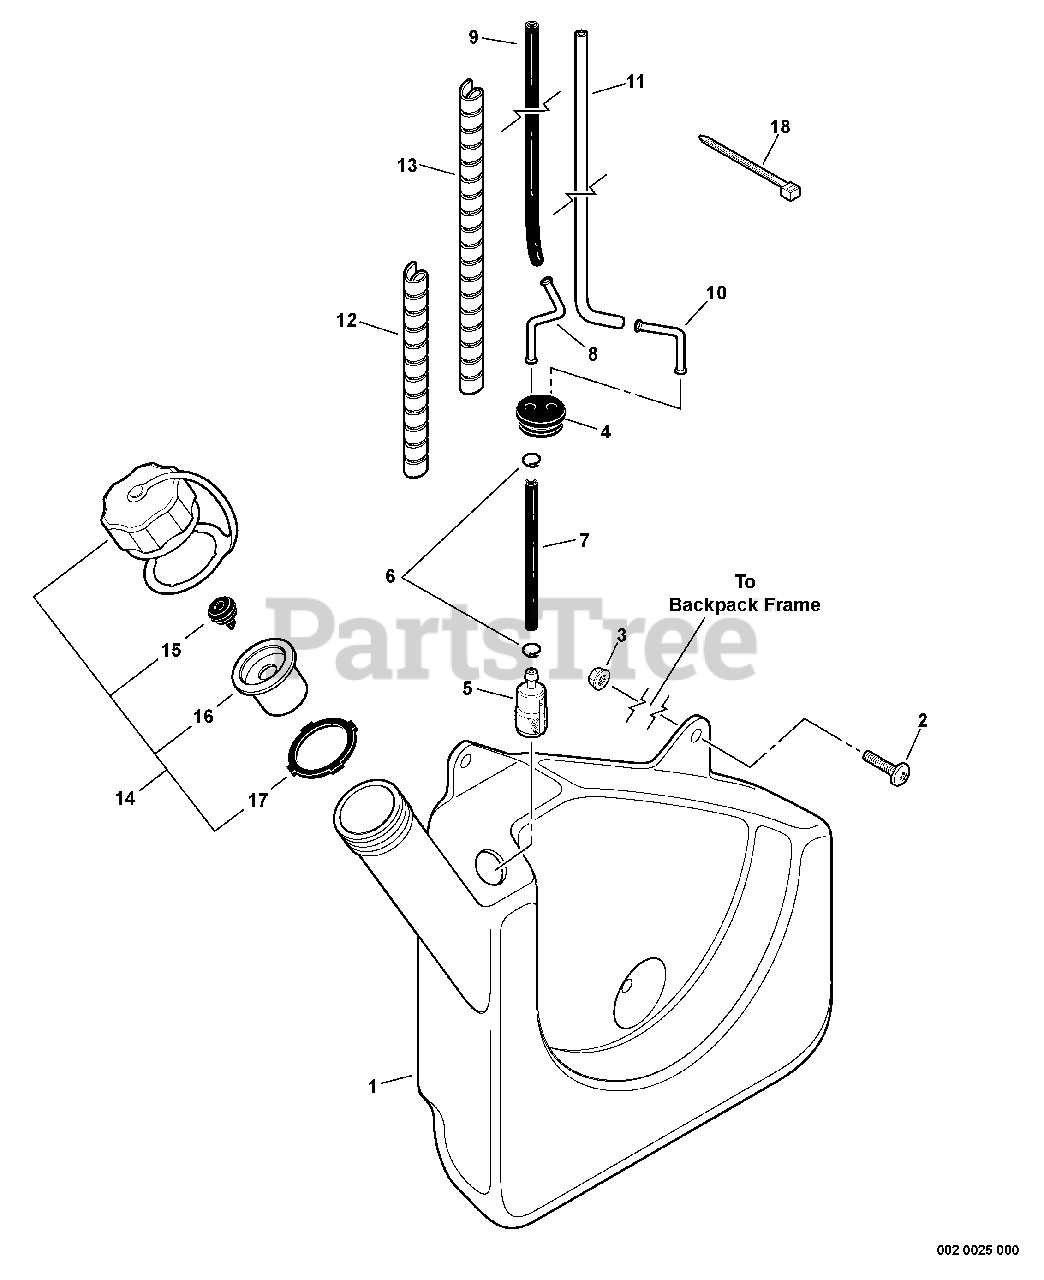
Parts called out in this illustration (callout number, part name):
1	TANK, FUEL
2	SCREW 5×20
3	NUT, FLANGE M5
4	GROMMET
5	FILTER, FUEL
6	CLIP Ø6.5 MM
7	PIPE, FUEL 3×6×280 MM
8	CONNECTOR, PIPE
9	PIPE, FUEL
10	CONNECTOR, PIPE
11	PIPE, FUEL
13	WRAP, SPIRAL
14	CAP ASSY, FUEL
15	VENT ASSY
16	HOLDER, VENT
17	GASKET, FUEL CAP
18	STRAP, TIE
